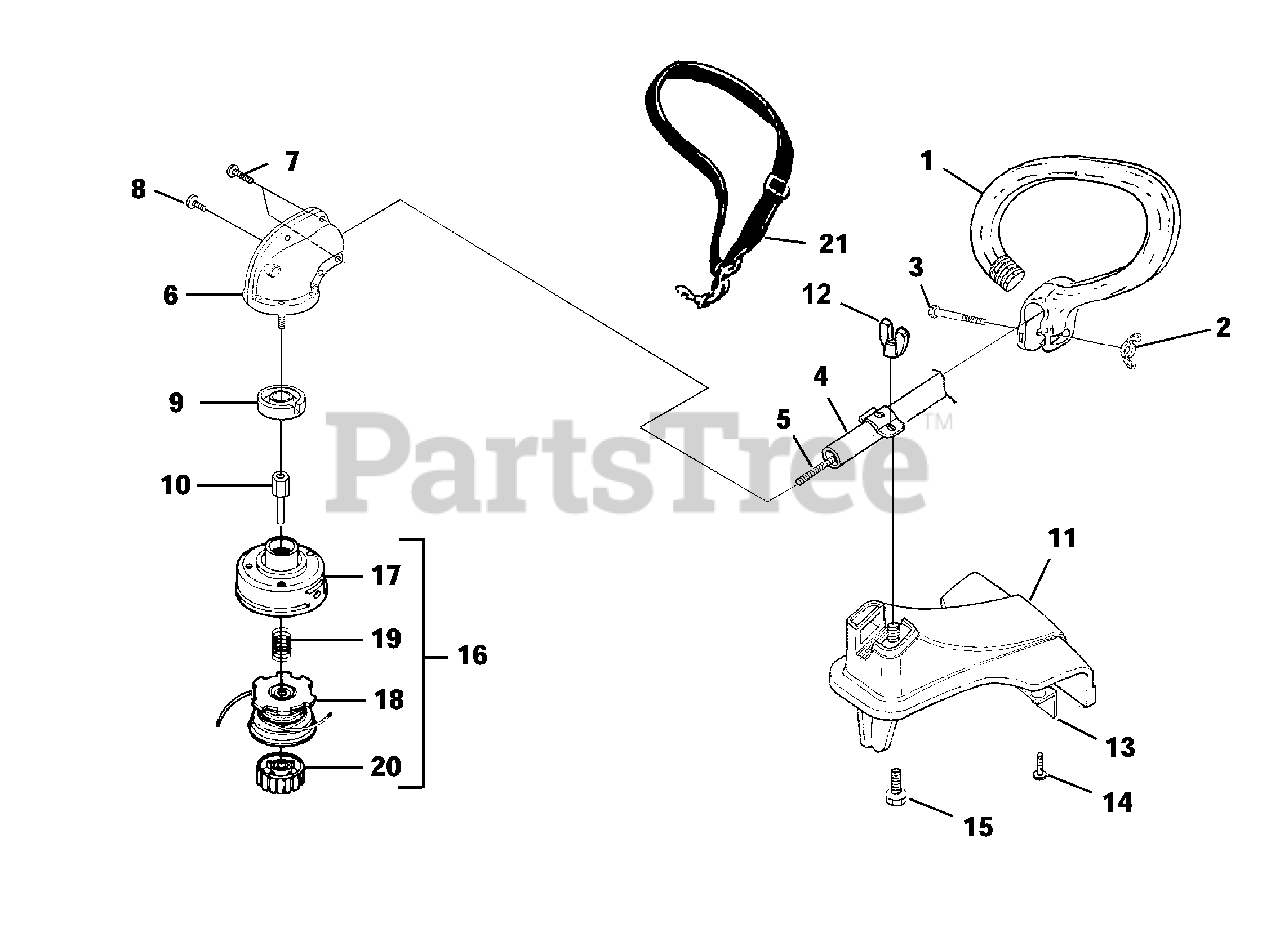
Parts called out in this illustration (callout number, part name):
1	HANDLE-Anti-Vibe
2	NUT-Wing, Washer Faced (1/4-20)
3	SCREW-Cap Hex Hd. (1/4-20 x 2")
4	DRIVESHAFT HOUSING ASSY.
5	SHAFT-Flexible
6	GEARHEAD
7	Screw, Taptite Hex Hd. (10-24 x 1/2")
8	Screw-Hex Hd. (10-24 x 5/8")
9	WASHER-Flanged
10	ADAPTER-Shaft
11	GRASS DEFLECTOR KIT
12	WING NUT
13	BLADE-Cut-off
14	SCREW-Mach.Hex Hd. (10-24 X 3/8")
15	SCREW-Square Head
16	STRINGHEAD-Complete (.080")
17	HOUSING & EYELET (Dual Line)
18	SPOOL & STRING (.080")
19	SPRING-Compression
20	RETAINER-Spool (R.H. Thread, Black)
21	HARNESS
